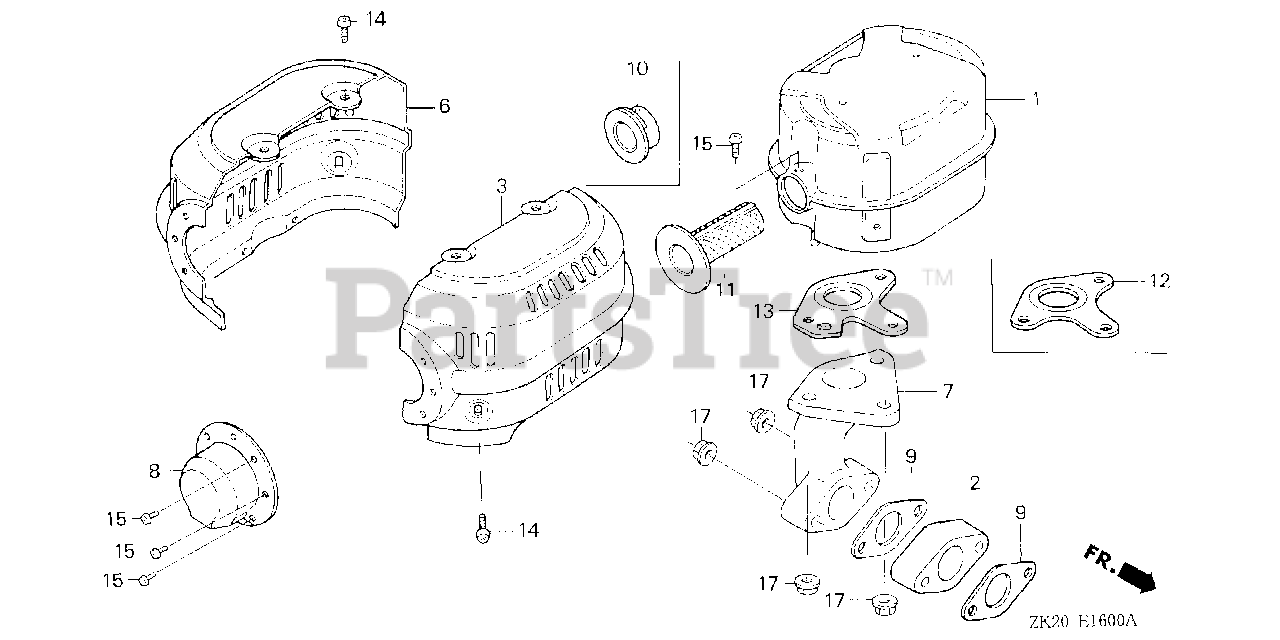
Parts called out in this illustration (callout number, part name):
1	MUFFLER
1	MUFFLER (SILENT)
3	PROTECTOR, R. MUFFLER (STD)
6	PROTECTOR, L. MUFFLER (STD)
7	PIPE, EX.
8	CAP, MUFFLER
9	GASKET, EX. PIPE
9	GASKET, EX. PIPE (WACKER)
11	ARRESTER, SPARK
13	GASKET, MUFFLER (ARRESTER)
14	SCREW, TAPPING (5X8)
15	SCREW, TAPPING (5X8)
15	SCREW, TAPPING (4X6)
17	NUT, FLANGE (8MM)
